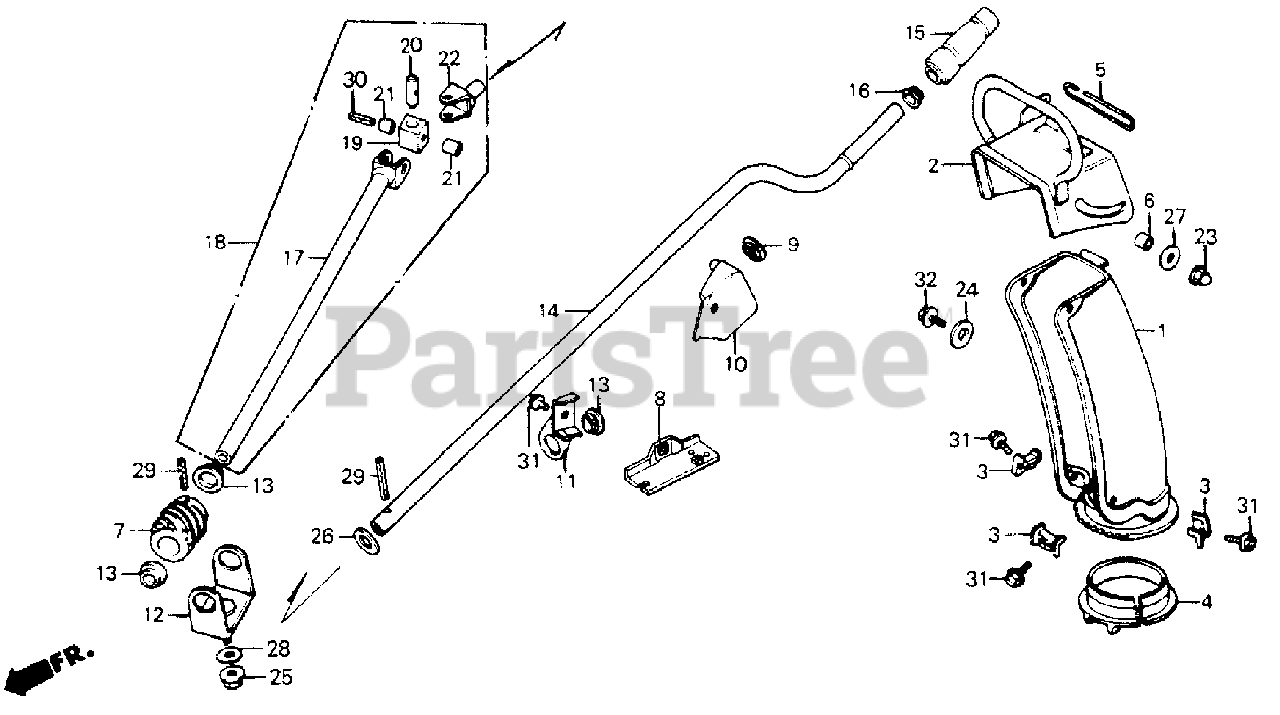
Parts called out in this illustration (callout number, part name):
1	CHUTE (NOT AVAILABLE)
2	GUIDE, CHUTE (NOT AVAILABLE)
3	PLATE, CHUTE SETTING (NOT AVAILABLE)
4	BUSH, CHUTE
5	PIN, CHUTE GUIDE
6	COLLAR, CHUTE GUIDE (NOT AVAILABLE)
7	GEAR, CHUTE DRIVE
8	HOLDER, HANDLE BRACKET
9	BUSH, CHUTE HANDLE
10	BRACKET A, CHUTE HANDLE
11	BRACKET B, CHUTE HANDLE
12	STAY, DRIVE GEAR
13	BUSH, DRIVE GEAR
14	HANDLE, CHUTE (UPPER)
15	GRIP, CHUTE HANDLE
16	BUSH A, CHUTE HANDLE
17	HANDLE, CHUTE (LOWER)
18	HANDLE, CHUTE (LOWER)
19	PIECE, JOINT
20	PIN A, JOINT
21	PIN B, JOINT
23	NUT, CAP (6MM)
24	SPRING, LEVER
25	NUT, FLANGE (8MM)
26	WASHER, PLAIN (16MM)
27	WASHER, PLAIN (6MM)
28	WASHER, PLAIN (8MM)
29	PIN, SPRING (4X28)
30	PIN, SPRING (4X32)
31	BOLT, FLANGE (6X12)
32	BOLT, FLANGE (6X14)
